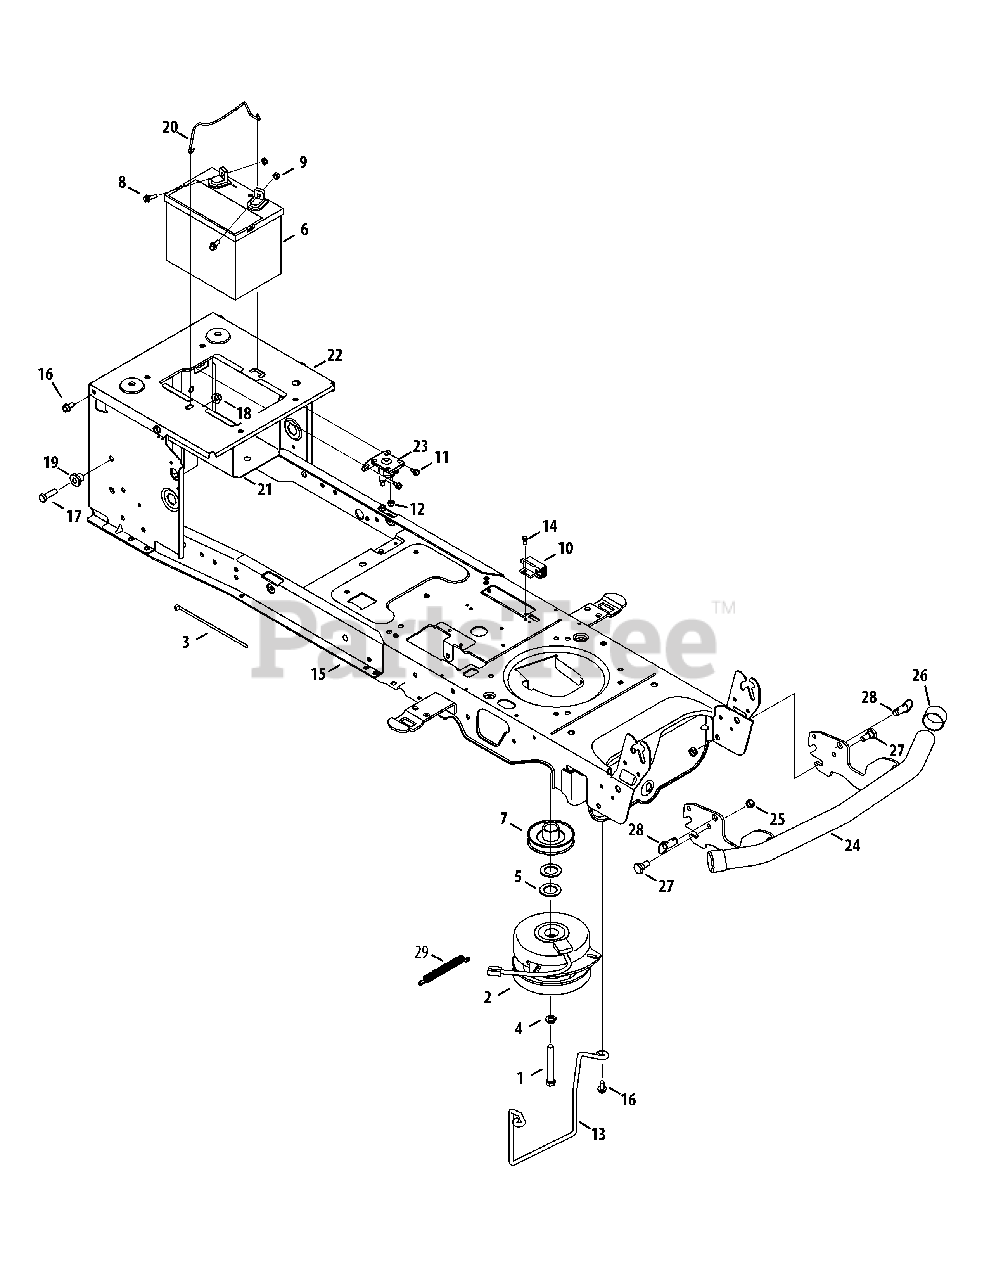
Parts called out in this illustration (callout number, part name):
1	Hex Screw, 7/16-20, 3.50, Gr5, Lock
2	Clutch, Electric PTO, 50" Deck
2	Clutch, Electric PTO, 54" Deck
3	Cable, Tie, 3/16 X .05 X 7.4
4	Washer, Lock, 7/16 , Regular Duty
5	Washer, Flat, 1.031 X1.620 X.095
7	Engine Pulley, Electric PTO
8	Hex Flange Screw, 1/4-20, .75, Gr5
9	Nut, Sems, 1/4-20
10	Switch, Interlock
11	Screw, Self-tapping, 1/4-20, 0.375
12	Nut, Flange Lock, 1/4-20, Nylon
13	Rod, Keeper
14	Screw, Shoulder, #10-32, .50
16	Screw, Self-tapping, 5/16-18, .750
17	Hex Screw, 3/8-16, 1.5, Gr2
18	Nut, Flange Lock, 3/8-16, Nylon
19	Spacer, Shoulder, .38 X 1.0 X .70
20	Rod, Battery
21	Tray, Battery
22	Bracket, Frame, Seat
23	Solenoid, 12V, 100 Amp, 4 term
25	Nut, Hex Lock, 3/8-16, GrB
26	Cap, Bumper
27	Bolt, Shoulder, .496 x .336, 3/8-16
28	Pin, Quick Release, 1/2 Dia x .50
29	Spring, Extn, .56 Dia X 5.52
